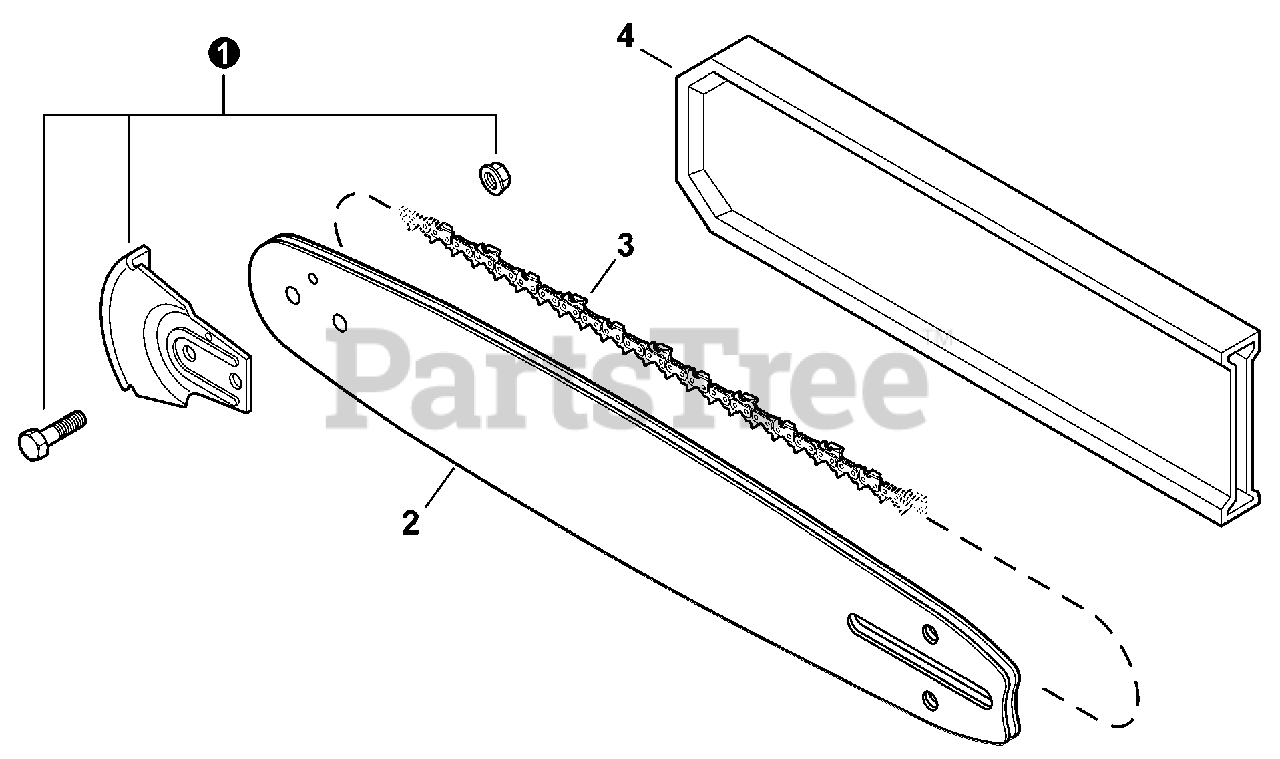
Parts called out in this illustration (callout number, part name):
1	KICK GUARD KIT
2	GUIDE BAR, 16"
2	GUIDE BAR, 18"
2	GUIDE BAR, 20"
2	GUIDE BAR, 24"
2	GUIDE BAR, 27"
3	SAW CHAIN - 16"
3	SAW CHAIN - 18"
3	SAW CHAIN - 20"
3	SAW CHAIN - 24"
3	SAW CHAIN - 27"
4	SCABBARD 16"
4	SCABBARD 18"
4	SCABBARD 20"
4	SCABBARD 24"
